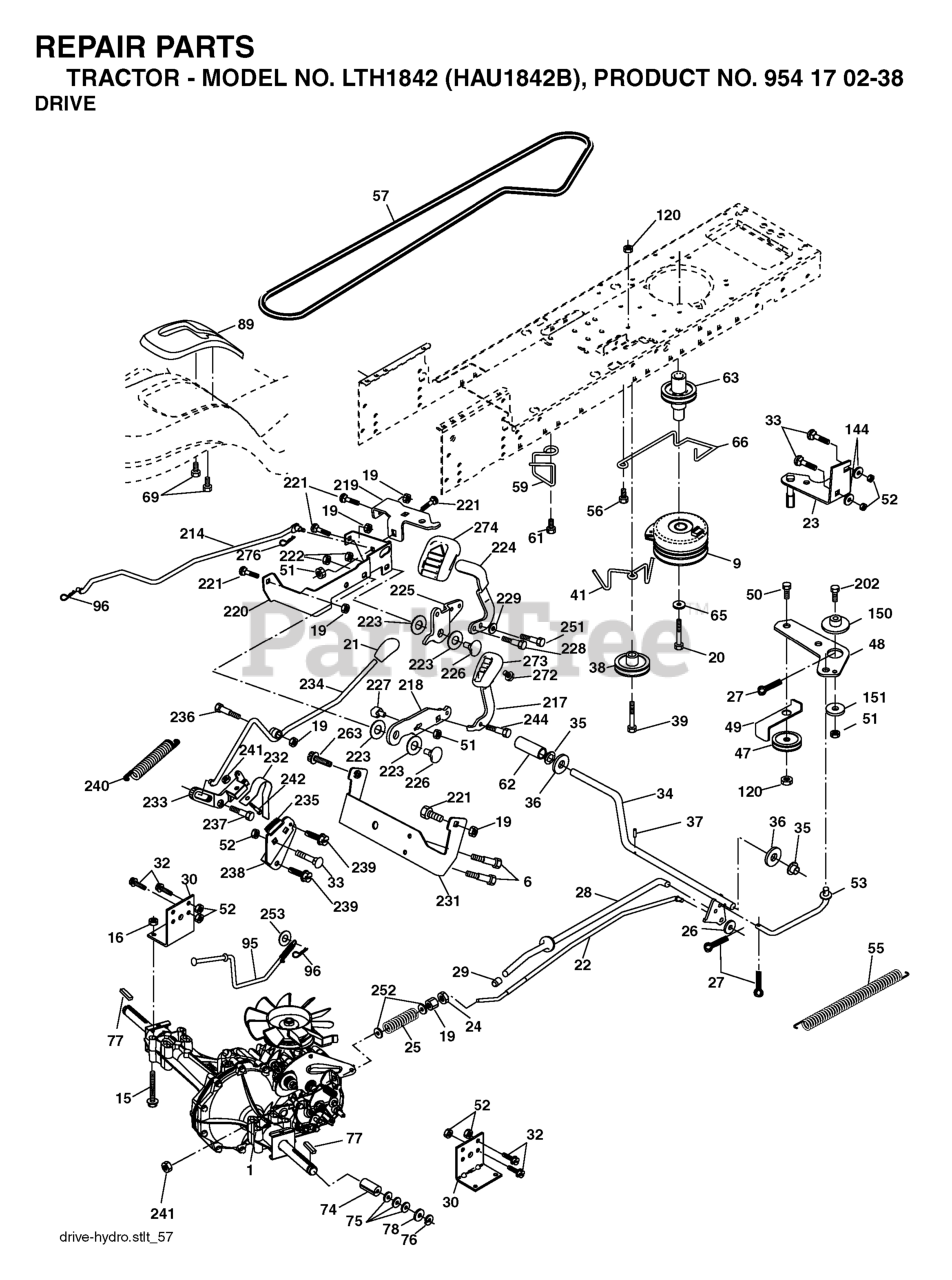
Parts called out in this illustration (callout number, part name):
6	SCREW 5/16"
9	ELECTRIC CLUTCH
15	BOLT HEX 5/16-18 GR 5
16	NUT.71038.31-18.HEX.NYLOCK
19	NUT
20	BOLT HEX
22	ROD.BRAKE.HG-0510.PEDAL.CONTRL
24	NUT
25	SPRING BRAKE ROD
26	WASHER
27	COTTER PIN
28	ROD, PARKING BRAKE
29	PLUNGER CAP
30	BRKT, TRNSXLE MNT 20"
32	BOLT
33	RP BOLT 5/16-18 X3/4 ZN/YEL GR
34	SHAFT, FOOT PEDAL
35	BEARING.NYLON
37	DRIVE PIN
38	PULLEY IDLER COMPOSITE
41	KEEPER, BELT IDLER
47	IDLER PULLEY
48	BELLCRANK, CLUTCH
49	RETAIN BELT
50	BOLT.3/8-16X1.50
52	LOCKNUT
53	LINK, CLUTCH LT
55	SPRING, RETURN LT
56	SCREW.3/8-16
57	DRIVE BELT, LTH & YTH TRACTORS
59	KEEPER, BELT CENTER
61	SCREW 3/8-16X.875
62	COVER, PEDAL (1 2)
63	PULLEY, ENGINE
65	LOCKWASHER
66	KEEPER BELT ENGINE
69	SCREW.HI-LO.CONSOLE
74	SPACER AXLE
77	SQUARE KEY
95	ROD BYPASS
96	RETAINER M
120	NUT LOCK FLG 3/8-16 UNC
144	Washer 11/32 x 5/8 x 16 Ga SD
150	SPACER, RETAINER
151	WASHER 12/32X2X10GA
214	LINK TRANSAXLE
217	PEDAL REVERSE
218	ARM CONTROL PEDAL REVERSE
219	BRACKET FREST PDL
220	BRACKET MTG.PDL CONTROL
221	Bolt - Rd. Hd. Sq. Neckiage 3/8 16 x 3/4
222	Nut, Crownlock Hex 7/16-14 unc
223	WASHER NYLON
224	PEDAL FORWARD
225	ARM CONTROL PEDAL FORWARD
226	BOLT PIVOT SPACER
227	CAM REVERSE PEDAL LT
228	BOLT SHOULDER
229	WASHER.SERRATED.5/16X.75
231	STRAP TORQUE
232	ACUATOR CRUISE DISENGAGE
233	PAWL CONTROL CRUISE
234	LEVER CONTROL CRUISE
235	SECTOR CONTROL CRUISE
237	SHOULDER BOLT 5/16-18TT
238	ARM MTG.CRUISE SECTOR
239	Screw 5/16-18 x 1/2 Hex, Self Tapping 5/16-18 x 1/2
240	SPRING RETURN CRUISE CONTROL
241	NUT CENTERLOCK
242	BOLT
244	CAPSCREW.HXHD.FLG.5/16-18X.625
251	SCREW 5/16-18X1
252	WASHER
263	SCREW, 3/8-16X3/4
272	SCREW, 5/16-18 X 1/2
274	COVER PEDAL FORWARD
276	CLIP RETAINER
